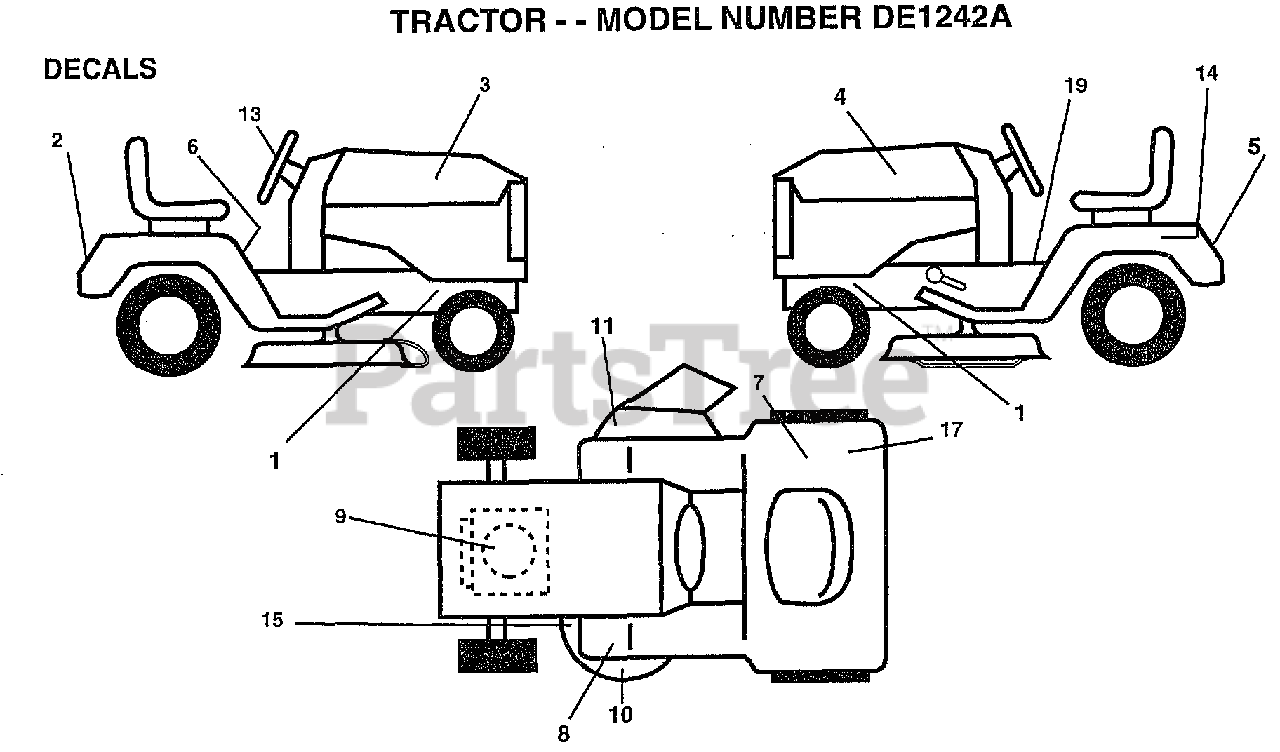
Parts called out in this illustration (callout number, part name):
1	"DECAL CHASSIS,HOT"
2	DECAL.FENDER.RH
3	DECAL.HOOD.RH
4	DECAL.HOOD.LH
5	DECAL.FENDER.LH
6	DECAL.READ.O.MANU
7	DECAL.EURO.ST.CE.
8	DECAL-BRAKE/CLUTC
9	DECAL, HP ENGINE
10	DECAL.DECK.MOWER
11	DECAL.DANGER.CUTF
13	DECAL.INST.STEERING
14	DECAL.BATRY.3-3908
15	"DECAL-SCHEM,BELT"
19	DECAL BRAK PARK
